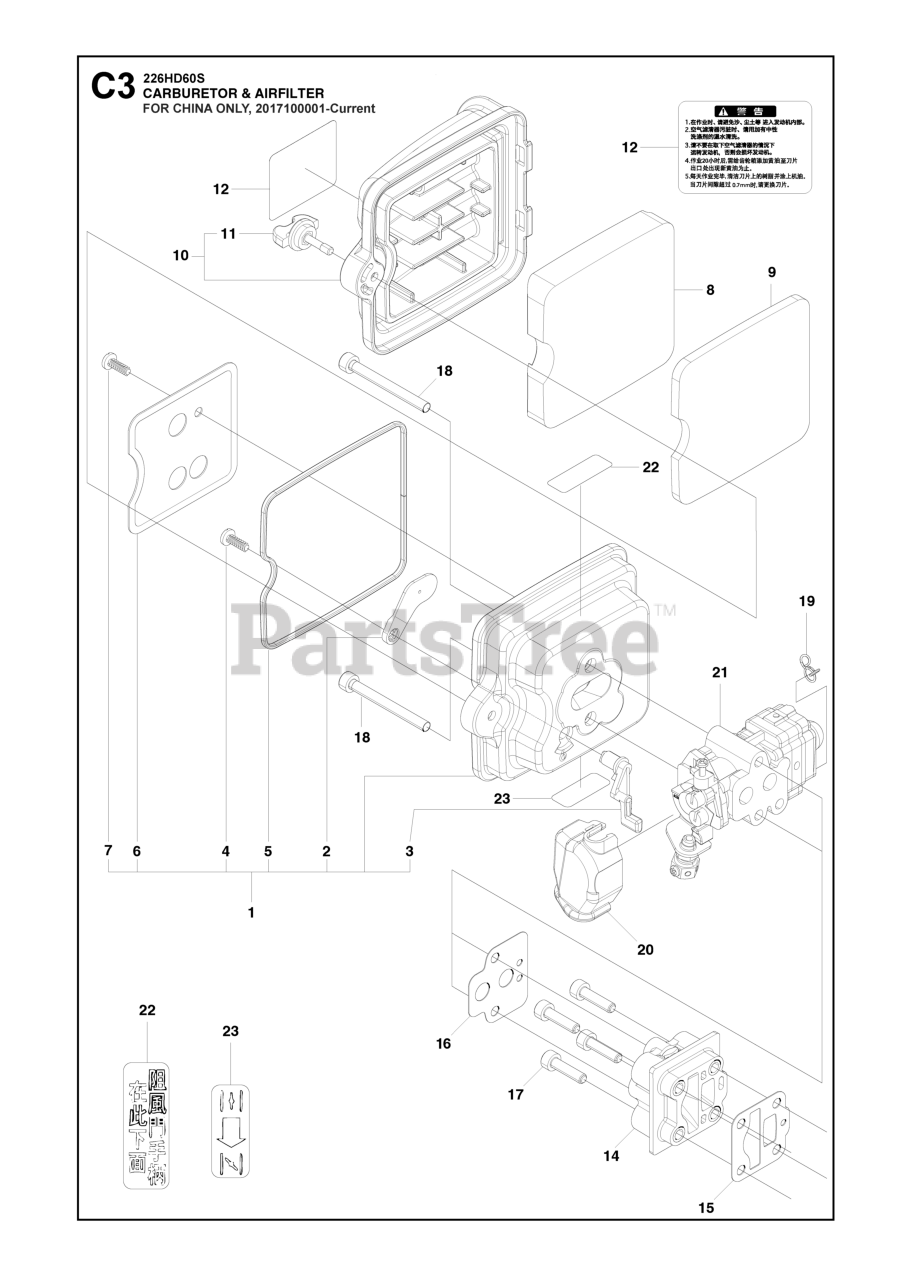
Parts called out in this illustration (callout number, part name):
1	FILTER HOUSING
2	PLATE.CHOKE
3	LEVER CHOKE
8	FILTER FOAM
10	COVER ASSY
12	LABEL.CAUTION
16	GASKET, CARB (RPLS T155113131)
21	CARBURETTOR ASSY
22	LABEL.CHOKE
